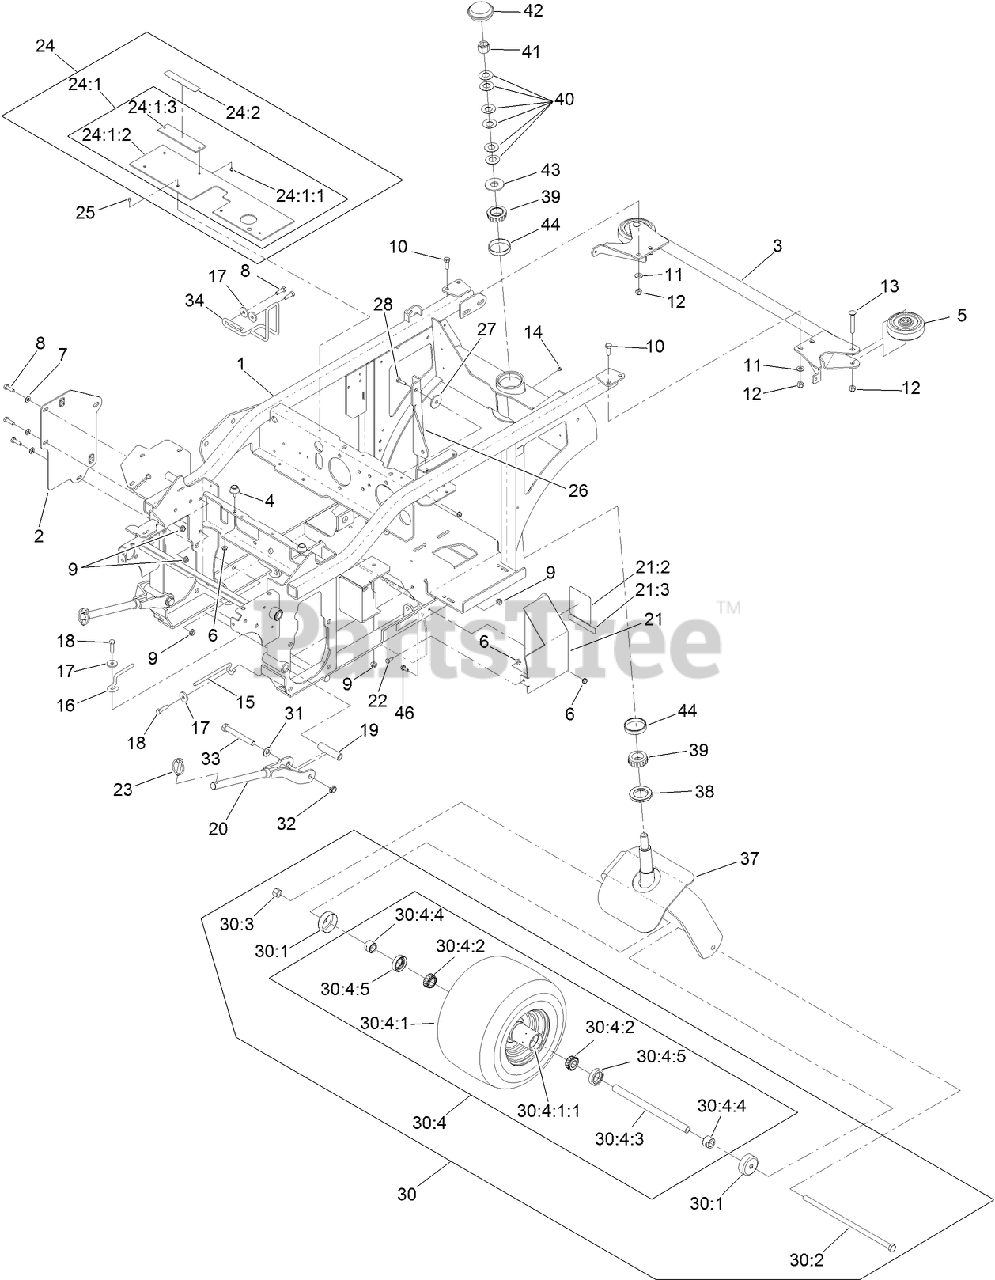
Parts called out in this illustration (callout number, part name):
1	FRAME ASM
2	PLATE-SUPPORT
3	BUMPER-REAR
4	BUMPER-RUBBER
5	ROLLER-BUMPER
6	NUT-HF
7	WASHER-PLAIN
8	SCREW-HH
9	NUT-HF
10	SCREW-HH
11	WASHER-FLAT
12	NUT-LOCK, NI
13	SCREW-CARR
15	GUIDE-BELT
16	GUIDE-BELT
17	WASHER
18	SCREW-HH
19	SPACER-WHEEL, SHORT
20	ROD-PUSH
21	DRIVE SHIELD ASM
21:2	DECAL-BELT ROUTING
21:3	DECAL-WARNING
22	SCREW-HH
23	PIN-LYNCH
24	LIFT SHIELD ASM
24:1	SHIELD-LIFT
24:1:1	RIVET-POP
24:1:3	PLATE-DECAL
24:2	DECAL-WARNING
25	RIVET-POP
26	BRACE-PTO
27	WASHER
28	SCREW-HH
30	WHEEL AND AXLE ASM
30:1	GUARD-SEAL
30:2	SCREW-HH
30:3	NUT-LOCK, NI
30:4	WHEEL AND BEARING ASM
30:4:1	WHEEL AND TIRE ASM
30:4:1:1	BEARING-CUP
30:4:2	BEARING-CONE, TAPER
30:4:3	AXLE CASTER ASM
30:4:4	SPACER-NUT
30:4:5	SEAL-CASTER
31	WASHER-FLAT
32	NUT-HEX
33	SCREW-HH
34	WLD-BELT GUIDE
37	FORK-REAR CASTER
38	SEAL-GREASE
39	BEARING-ROLLER, CONE TAPER
40	WASHER-BELLVILLE
41	NUT-LOCK, NI
42	CAP-GREASE
43	WASHER-FLAT
44	CUP-TAPERED, ROLLER BEARING
46	SCREW-HHF
